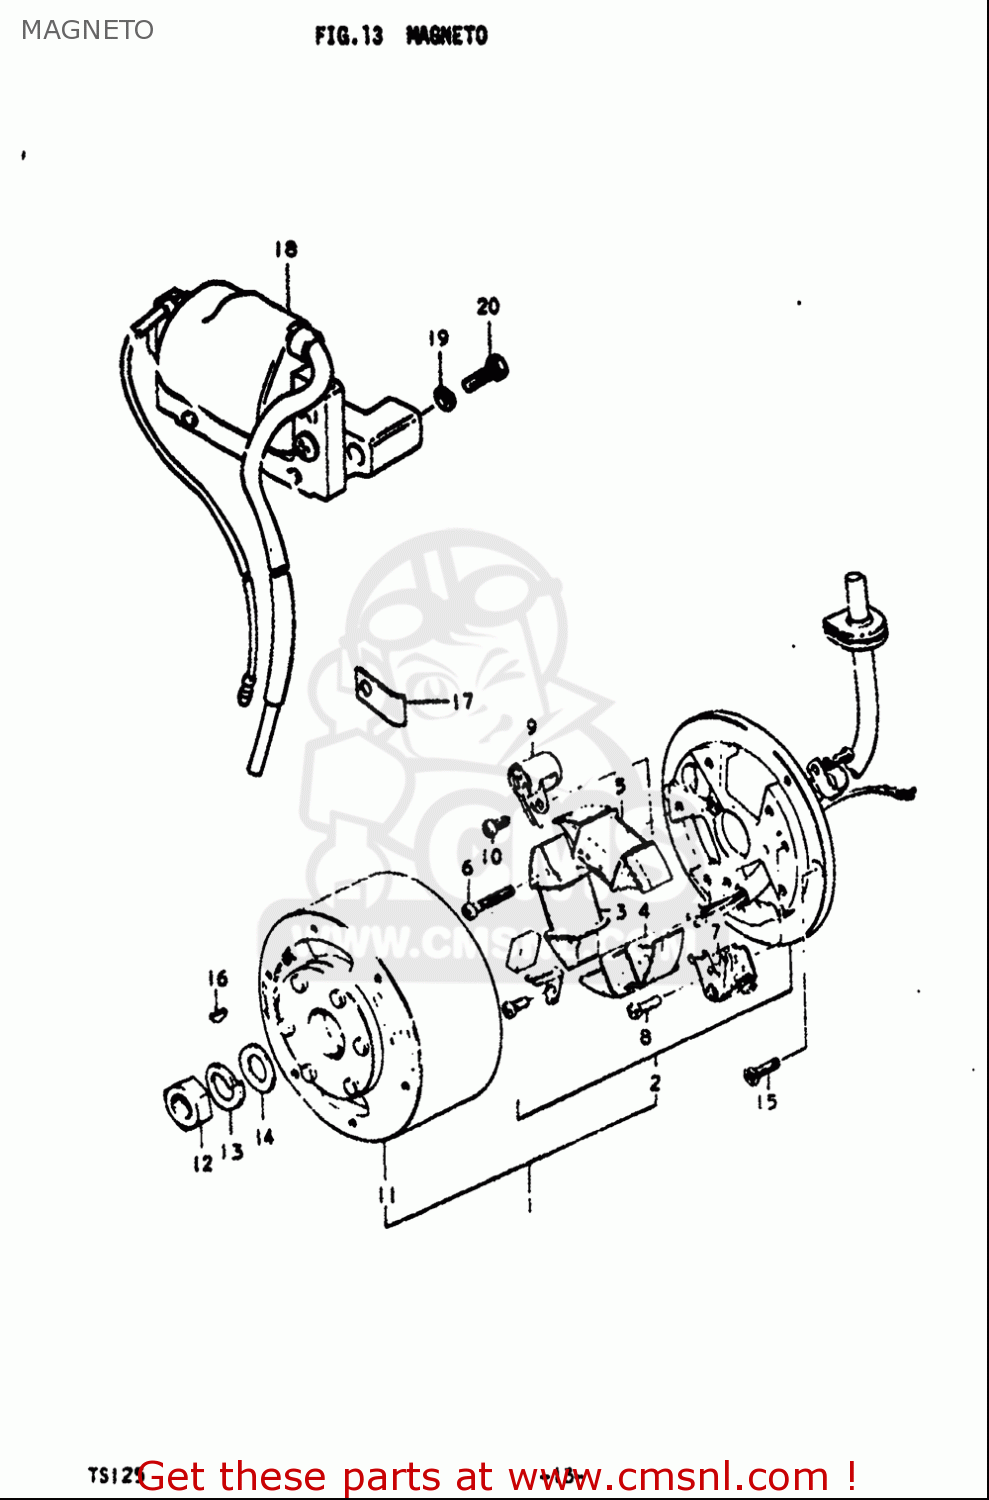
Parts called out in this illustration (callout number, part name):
5	COIL,PRIMARY
6	SCREW(4X30)
7	POINT ASSY,CONTACT
8	.SCREW
9	CONDENSER
10	SCREW
12	NUT
13	WASHER,LOCK
14	WASHER
15	SCREW
16	KEY
17	CLAMP(L:65)
18	COIL ASSY,IGNITION
19	WASHER,LOCK
20	BOLT
